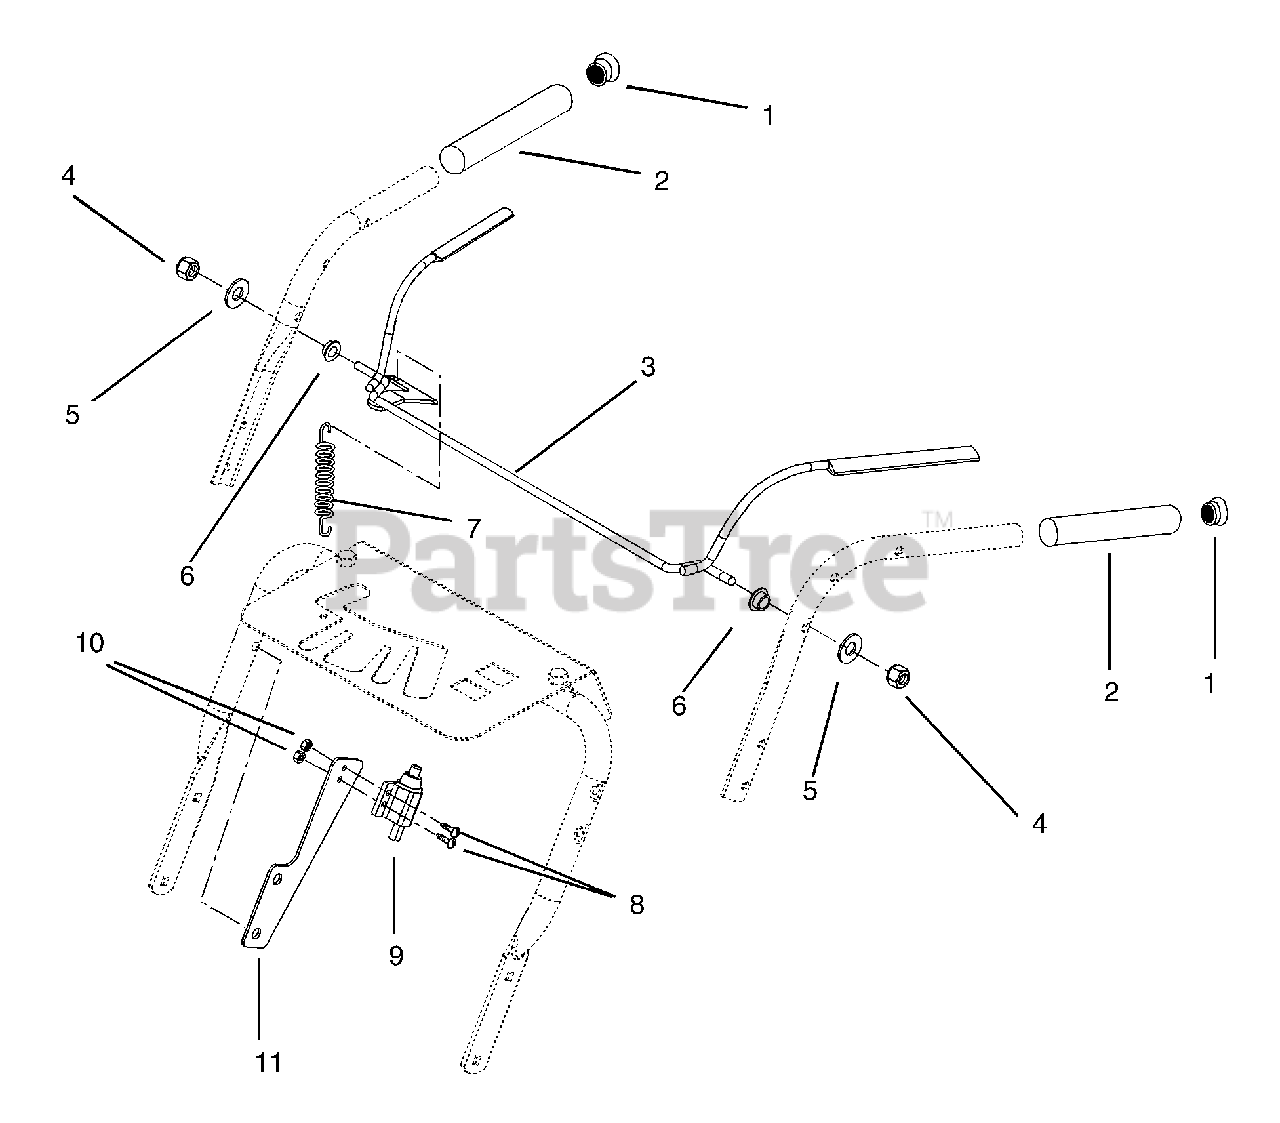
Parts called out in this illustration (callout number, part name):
1	Cap- Vinyl
2	Grip-Handle
3	Handlebar Left Hand
4	Nut-Locking-Center .31-18
5	Washer-Flat-Steel .344 x .688 x .065
6	Bushing-Flange
7	Spring-Tension .041 x .50 x 1.75
8	Screw-Machine 10-24 x .75
9	Switch-Single Pole N.O.with Cover
10	Nut-Locking-Nylon 10-24
11	Bracket-Switch Mounting
